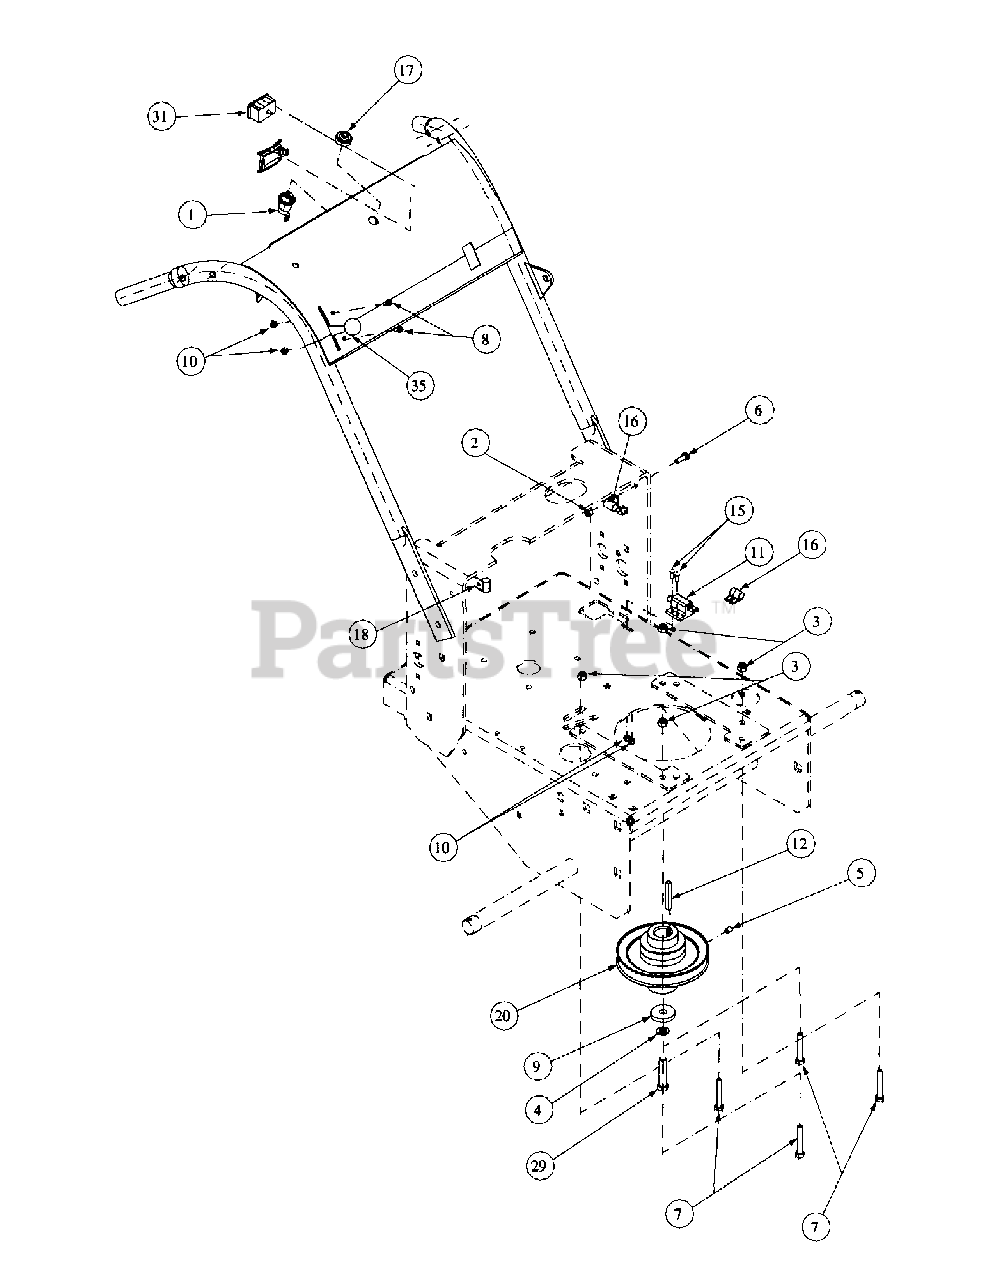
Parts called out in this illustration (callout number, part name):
1	Single Ignition ON/OFF Switch
2	Lock Nut, Nylon Insert, 1/4-20
3	Nut, 5/16-18, Nylock
4	Lock Washer, 7/16 Zinc
5	Nylock Screw, 5/16-18 x 3/8
6	Hex Cap Screw, 1/4-20, .75
7	Hex Cap Screw, 5/16-18 x 2
8	Screw, Hex Washer, 10-32 x 1/2
9	Clutch Washer
10	Lock Nut, Nylon Insert, 10-32
11	Delta Switch
12	Key Stick, 1/4 x 1/4 x 2
13	Harness Wire
14	Engine Spacer, RH
15	Machine Screw, 10-32 x 5/8
16	Support Clamp Tubing, 1/2"
17	Nut, w/Cap, 5/8-32, Ignition
18	Support Clamp, 3/8 OD
19	Engine Deck Assembly
20	Double Pulley Gear
21	Belt
22	Engine, 16HP V-Twin, Briggs
23	Capscrew w/Lock Washer, M8 x 1.25 x 2
24	Debris Guard, Vanguard Engine
25	Screw, M6 x 1.0 x 12mm
26	Screw Hex Flange, M5 x 1.0 x 8mm
27	Debris Guard Bracket
29	Capscrew, 7/16-20 x 2"
30	Hydro Handle Assembly
31	Hour Meter
32	Harness Hourmeter
33	Harness Assembly, B&S Adapter
34	Engine Spacer, LH
35	Throttle Control, 42.25
36	Muffler, 16/18/20/21/23, Vanguard
37	Manifold, 16/18/20, Vanguard
38	Muffler Clamp, 1.25 ID
